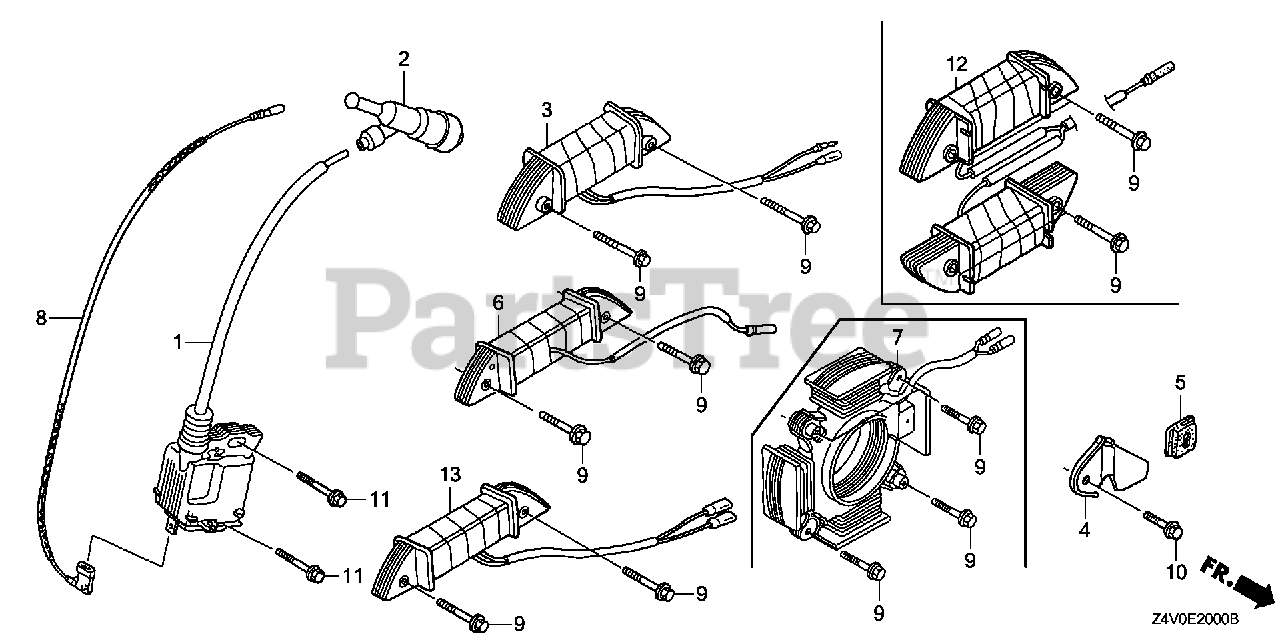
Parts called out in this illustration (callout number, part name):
1	COIL ASSY., IGNITION (TEC)
2	CAP ASSY., NOISE SUPPRESSOR (TEC)
8	WIRE, STOP SWITCH (370MM)
11	BOLT, FLANGE (6X25) Use up to Engine SN 2056819.
